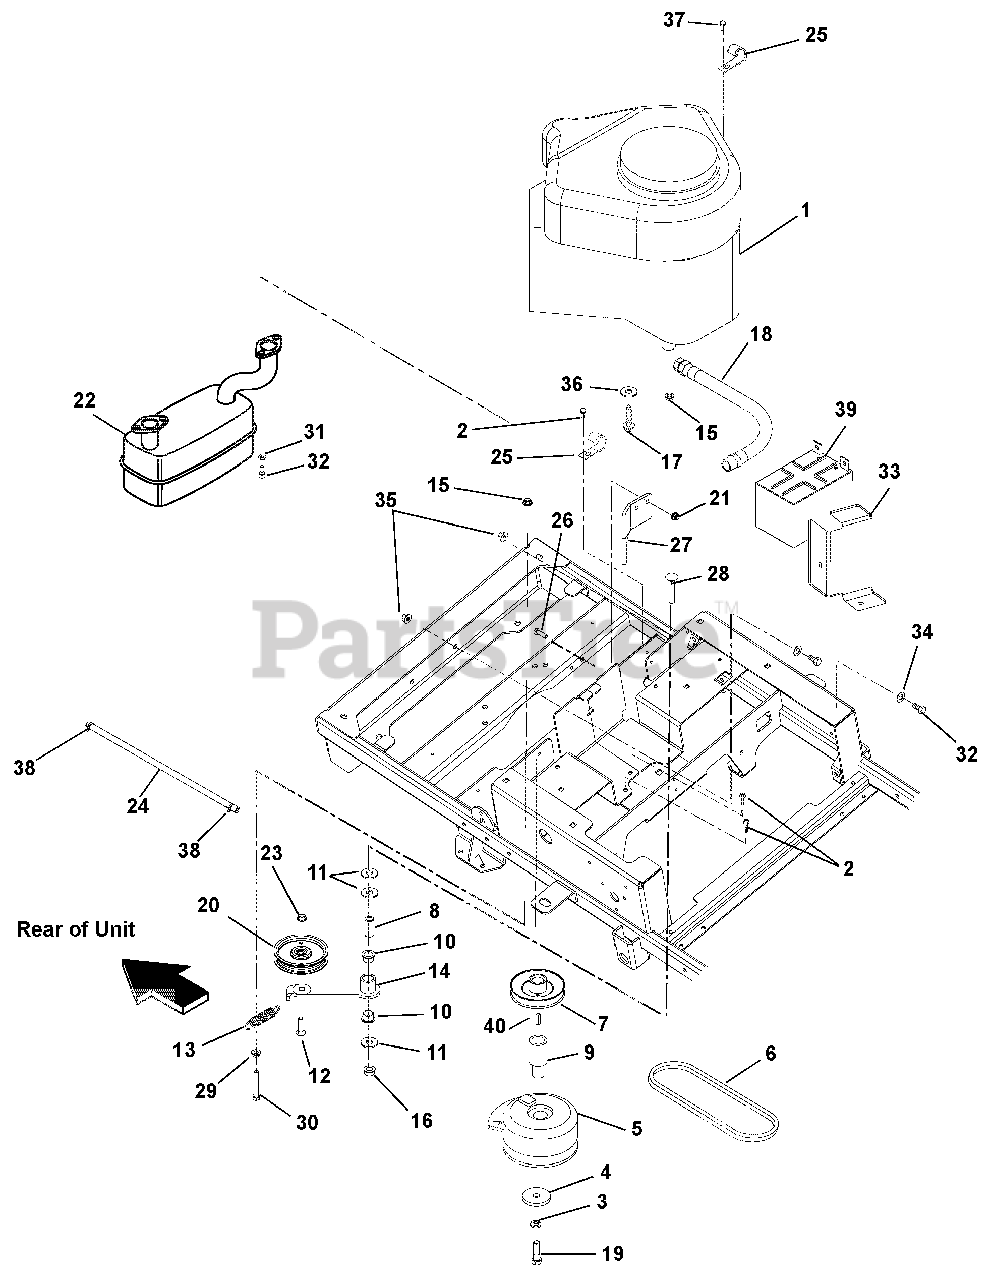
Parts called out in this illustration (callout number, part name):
1	ENGINE, KAWASAKI FR651V
2	SCR-TAP .25-20X.37 HWH YWZ TR
3	WSHR-LK .44X.109 REG YWZC
4	WSHR-FL-STL .469X2.00X.25 YWZC
5	CLUTCH,105FTLB MONOPOLE 6.83"
6	V-BELT, HA-WRAPPED
7	PULLEY, V-1" ID X 4.50" OD
8	BSHG-SLV .500X.750X1.560
9	EXT-CRANKSHAFT LOWER
10	BSHG-FLG 0.75X0.875X.625X1.125
11	WSHR-FL-STL.563X1.38X.109YWZC
12	BLT-RDHDSQNK .38-16X1.50 G5YZ
13	SG-TENS .105X.812X3.88 WLD 15
14	WMT, GROUND DRIVE IDLER ARM
15	NUT-LK-NYL-FLG .38-16 YWZC
16	NUT-LK-TOP-FLG .50-13 YWZC
17	BLT-HEX.38-16X1.25FTHG5 EP30YZ
18	OIL DRAIN HOSE
19	BLT-HEX .44-20X4.50 GR8 YWZC
20	ASM, 4" IDLER (.75 WIDE)
21	NUT-LK-NYL-FLG .31-18 YWZC
22	MUFFLER, TWIN
23	NUT-LK-TOP-FLG .38-16 YWZC
24	HOSE, .25 LOW-PERM BULK GAS
26	BLT-HEX .31-18X1.00 GR5 YWZC
27	CLUTCH STOP
28	BLT-RDHDSQNK .50-13X2.50 G5YZ
29	NUT-SPNLK-FLG .375-16 YWZC
30	BLT-HEX .38-16X2.50 GR5 YWZC
31	WSHR-LK .31X.078 REG YWZC
32	BLT-HEX .25-20X.75 GR5 YWZC
33	BRKT, BATTERY HOLDER
34	WSHR-FL-STL.281X.62X.065 YWZC
35	NUT-KEPS .250-20
36	WSHR-FL-STL.406X.812X.065 YWZ
37	BLT-HEX .38-16X.75 GR5 YWZC
38	CLAMP, FUEL LINE
39	BATTERY, 12V; 215 CCA GEP
40	KEY-STR .25X2.0X.25
